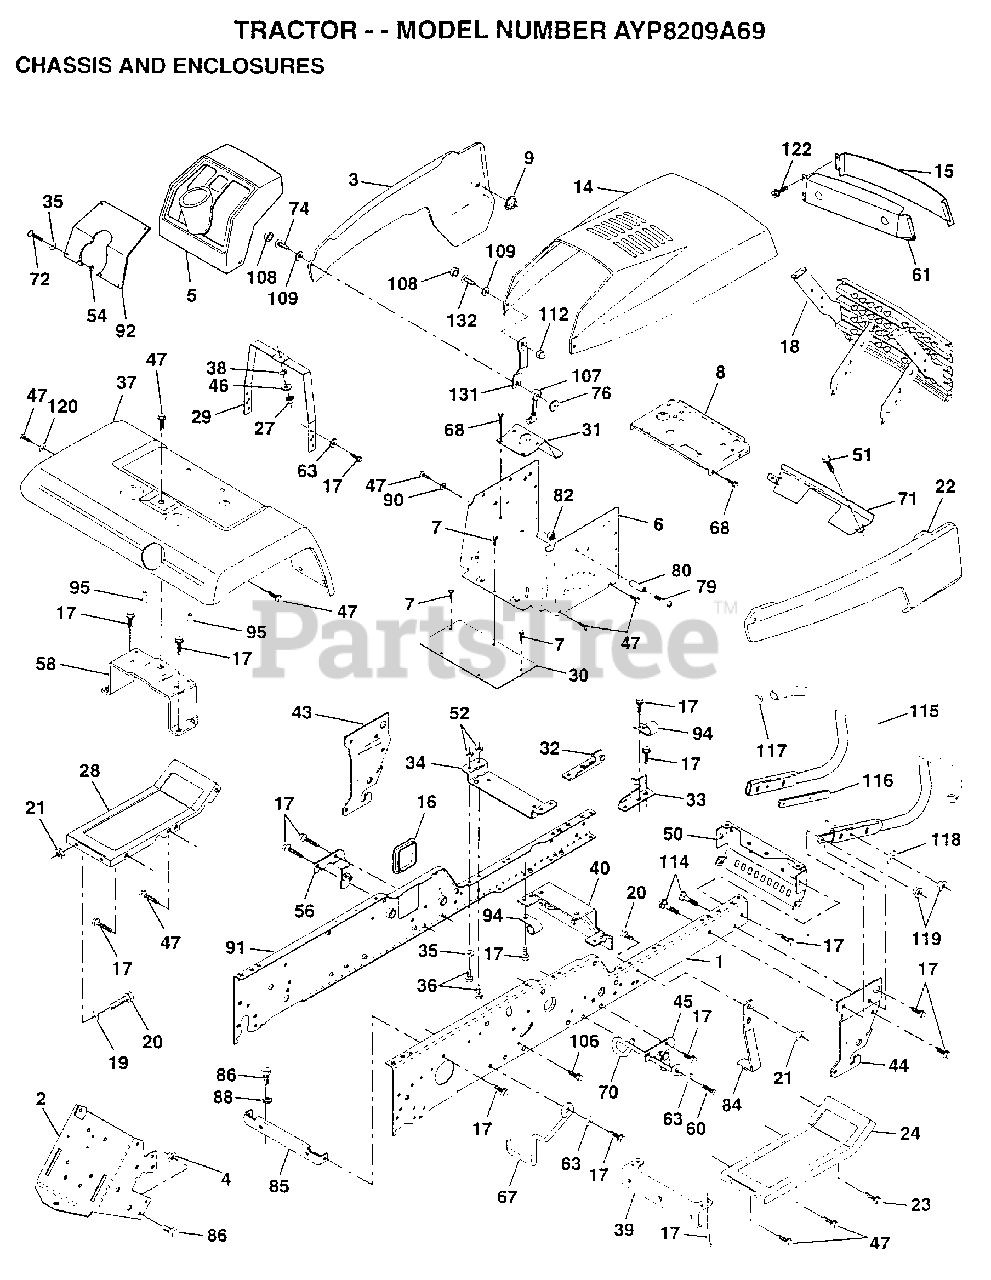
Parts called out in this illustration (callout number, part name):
1	"RAIL,FRAME RH"
2	DRAWBAR GT
3	"PANEL,ASM SIDE LH"
4	NUT GTV
5	DASHBOARD BLACK
6	"DASH AS.,LOWER"
7	SCREW
8	SUPPORT.DASH.BTRY
9	PAL NUT LT
14	"HOOD ASM.,PNT"
15	LENS.BAR.CLEAR
16	COVER ACCESS
17	SCREW
19	WASHER
20	BOLT
22	PANEL ASM.SIDE RH
23	SCREW GTV
24	FOOTREST.RH.LT/GT
26	SCREW
28	FOOTREST.LT.LT/GT
29	DASH.SUPT.YP/HUSQ
30	SADDLE.SCR.6SP
31	BRAKET.SUPT.STEER
32	BRACKET ASM FRAME
33	BRACKET ASM FRAME
34	BRACKET.ENG.SUPT.
35	WASHER
36	BOLT
37	"FENDER,RH"
38	LOCKWASHER
39	BRACKET.AXLE.FRT.
43	BRACKET.SUS.FT.LH
44	BRACKET.SUS.FT.RH
46	WASHER PM
47	SCREW LT
50	BRACKET.CHASSIS.
51	SCREW CRT
57	NUT
58	BRKT.ASM.FENDER
60	SCREW
61	BEZEL.ASM.
63	WASHER
67	GUIDE BELT TRANS
68	SCREW LT
70	GUIDE.BELT.MID.SP
72	SCREW
74	SCREW
75	LOCKWASHER
76	WELDNUT
79	SCREW
80	SPACER LT
81	WASHER
84	STOP.OVER.CENTER
85	BRACKET.SUPT.TRAN
86	BOLT
88	LOCKWASHER
90	LOCKWASHER
92	PLATE SLKSCR YP
93	SCREW LT
94	CLIP GTV
95	NUT-PUSH YT
107	HOOD LATCH T
108	SNAP CAP LT
109	WASHER LT
112	ACORN NUT RB
114	BOLT.3/8-14X1.25
115	BUMPER.ASM.W/PY
116	BRACKET.EXT.BUMP.
117	PLUG.PLASTIC
118	WASHER
120	WASHER HYT
124	NUT
131	BKT.SPT.HOOD/PANL
